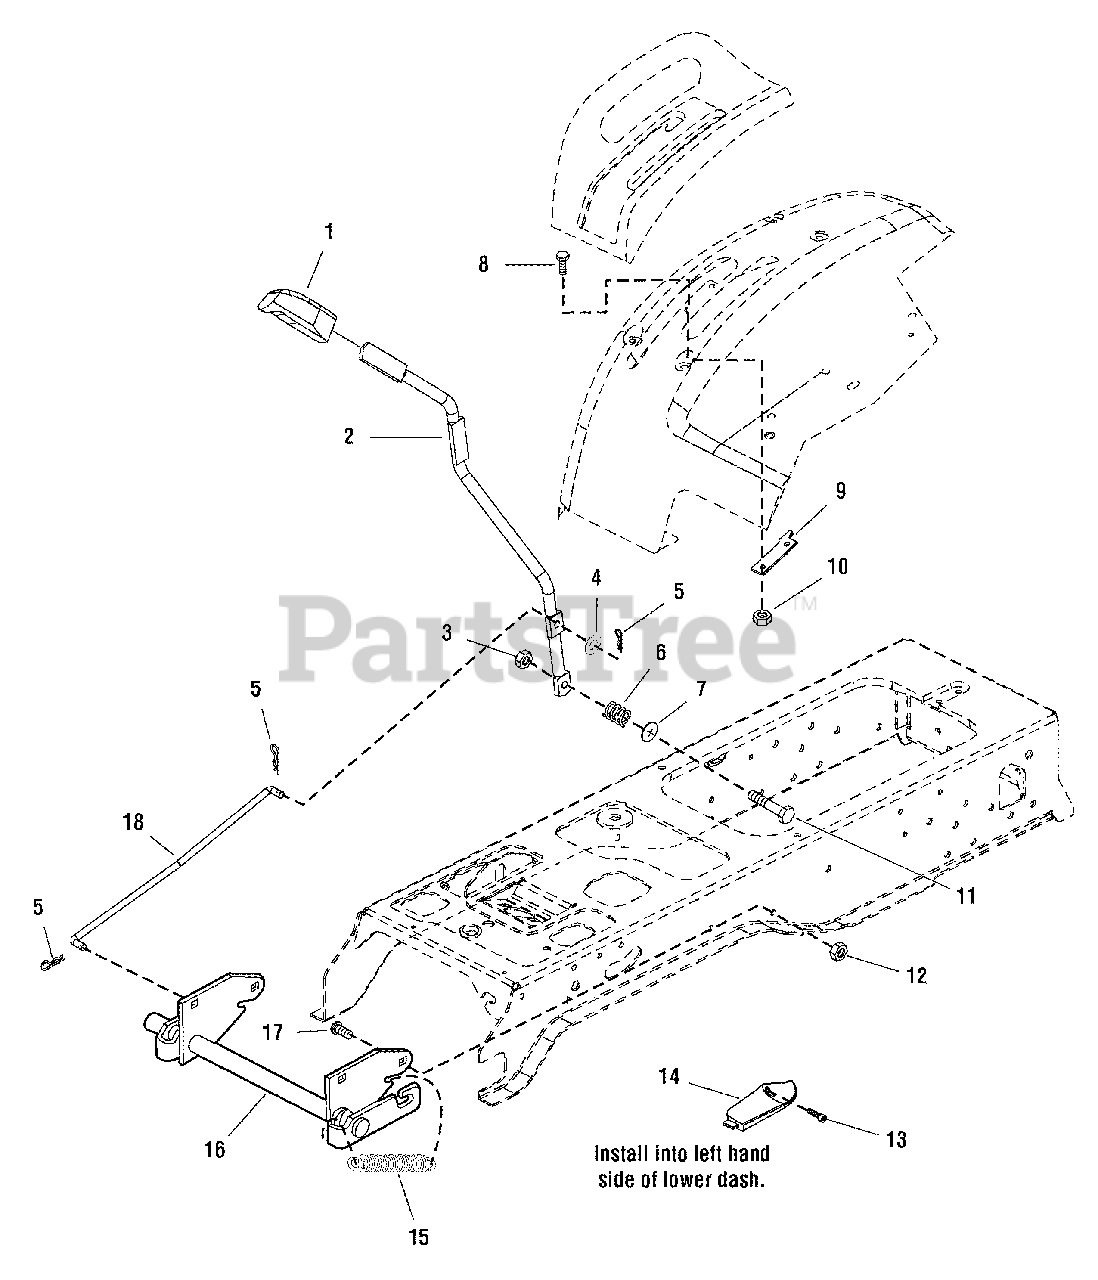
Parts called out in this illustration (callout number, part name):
1	GRIP, Black Vinyl
2	ROD, Lift Lever with Flats
3	NUT, Hex Flange Lock, 3/8-16
4	WASHER
5	PIN, Quick
6	SPRING, Compression
7	NUT, Push, 3/8
8	CAPSCREW, Hex Head, 1/4-20 x 3/4
9	QUADRANT
10	NUT, Hex Lock ESNA, 1/4-20
11	CAPSCREW, Hex Head, 3/8-16 x 2
12	NUT, KEPS Lock, 5/16-18
13	SCREW, Torx Head, # 8-16 x 1/2
14	COVER, Dash
15	SPRING
16	LIFT SHAFT ASSEMBLY,
17	CARIAGE BOLT, 5/16-18 x 3/4
18	ROD, Lift
